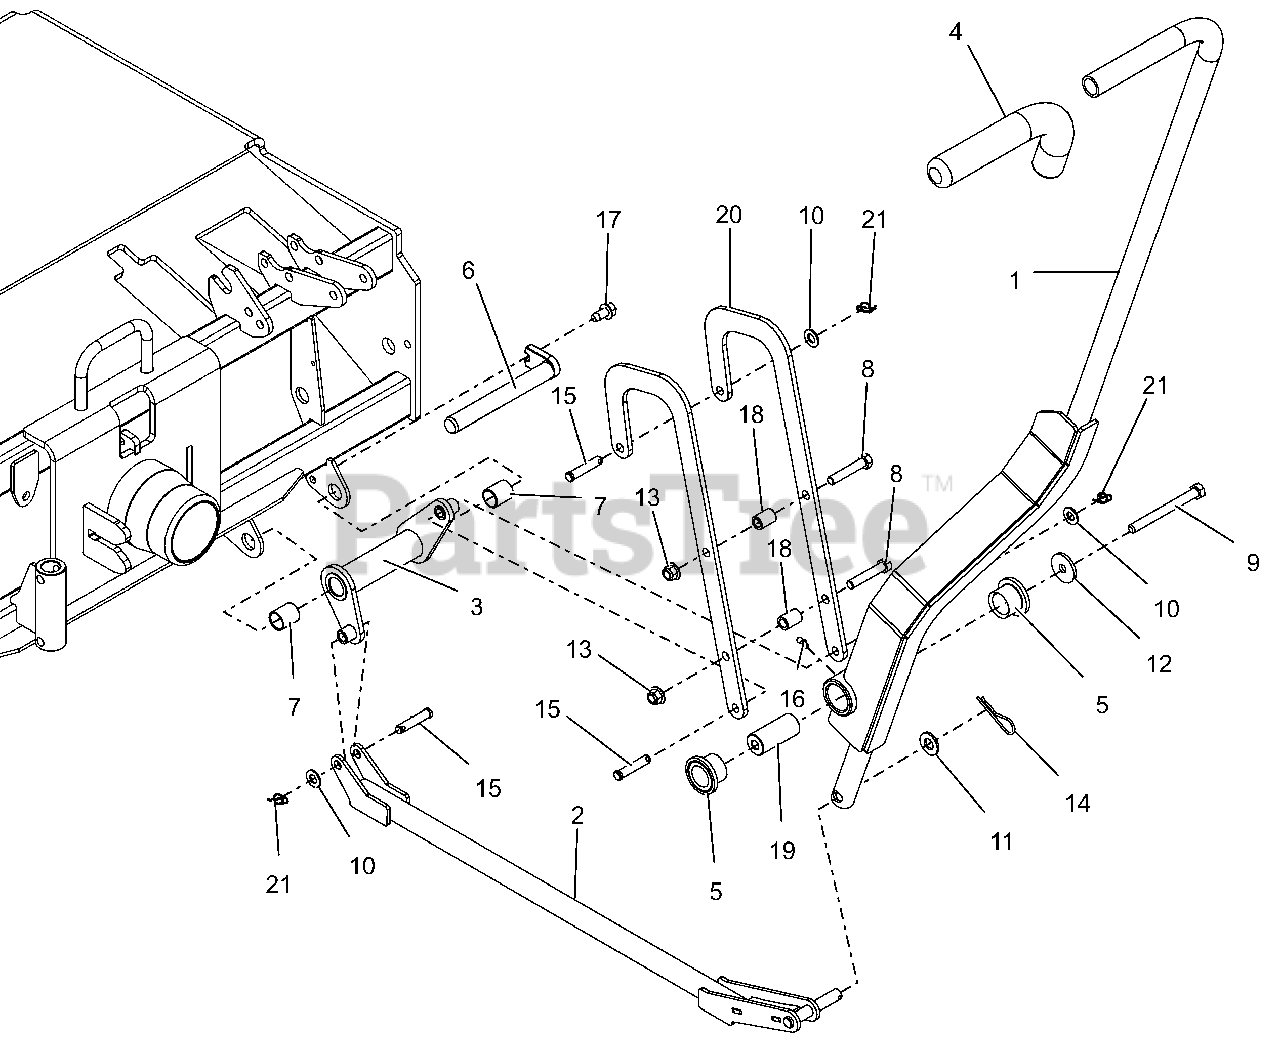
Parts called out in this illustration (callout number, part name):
1	WLDMT, LIFT HANDLE
2	WLDMT, LOWER LINK
3	WLDMT, LIFT BRKT
4	GRIP, HANDLEBAR 1.00X1.38X11.3
5	BRG, FLG 1.00 X 1.25 X 1.00
6	PIN, MOWER MTG
7	BRG, .750 X .875 X 1.000
8	BLT,HEX .38-16X2.00 G5 ZCC
9	BLT,HEX M10-1.5X100 G8.8 ZCC
10	WSHR,FLT .406X.812X.065 ZCC
11	WSHR,FLT .531X1.062X.095 ZCC
12	WSHR,FLT .406X1.375X.135 ZCC
13	NUT,NYL-FLG .38-16 GF ZCC
14	PIN, HAIR-#7 .094X2.31 ZC120
15	PIN-CLEV .370X1.75
16	FTG-LUBE .25-28X.256 SST
17	SCR,TAP .375-16X.75 HWH TR ZCC
18	TUBE, SPACER
19	SPCR, PIVOT
20	ARM, LIFT
21	RING, RUE .375 X .054 X 1.254
